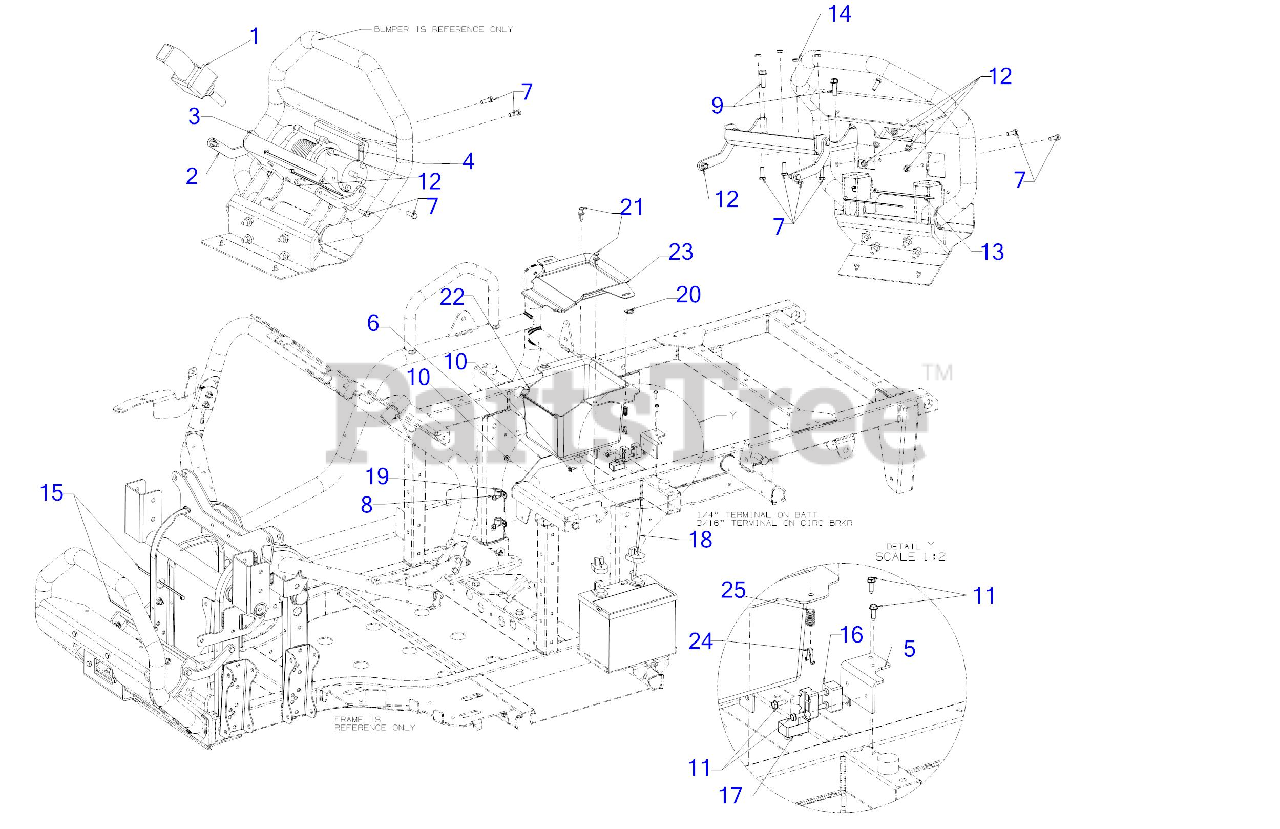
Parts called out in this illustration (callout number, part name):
1	WINCH ASSEMBLY
2	SUPPORT PLATE
3	WINCH MOUNT BRACKET
4	FAIRLEAD MOUNT BRACKET
5	CIRCUIT BREAKER BRACKET
7	SCREW 5/16-18 x 1.0 GR5
8	SCREW 1/4-20 X.500
9	SCREW 3/8-16 x 1.25 GR5
10	SCREW M6-1 x .625
11	SCREW #10-16 x .625
12	FLANGE LOCK NUT 5/16-18
15	7" CABLE TIE
16	CIRCUIT BREAKER 50 AMP
17	CIRCUIT BREAKER BOOT (RED)
18	WIRE LEAD 10"
19	WIRE CLAMP 1/2" ID
20	1/4 TURN PANEL HANDLE
21	PLASTIC RIVET
22	UNDER SEAT STORAGE CONTAINER
23	UNDER SEAT COVER LID
24	SPRING CLIP
25	COMPRESSION SPRING
